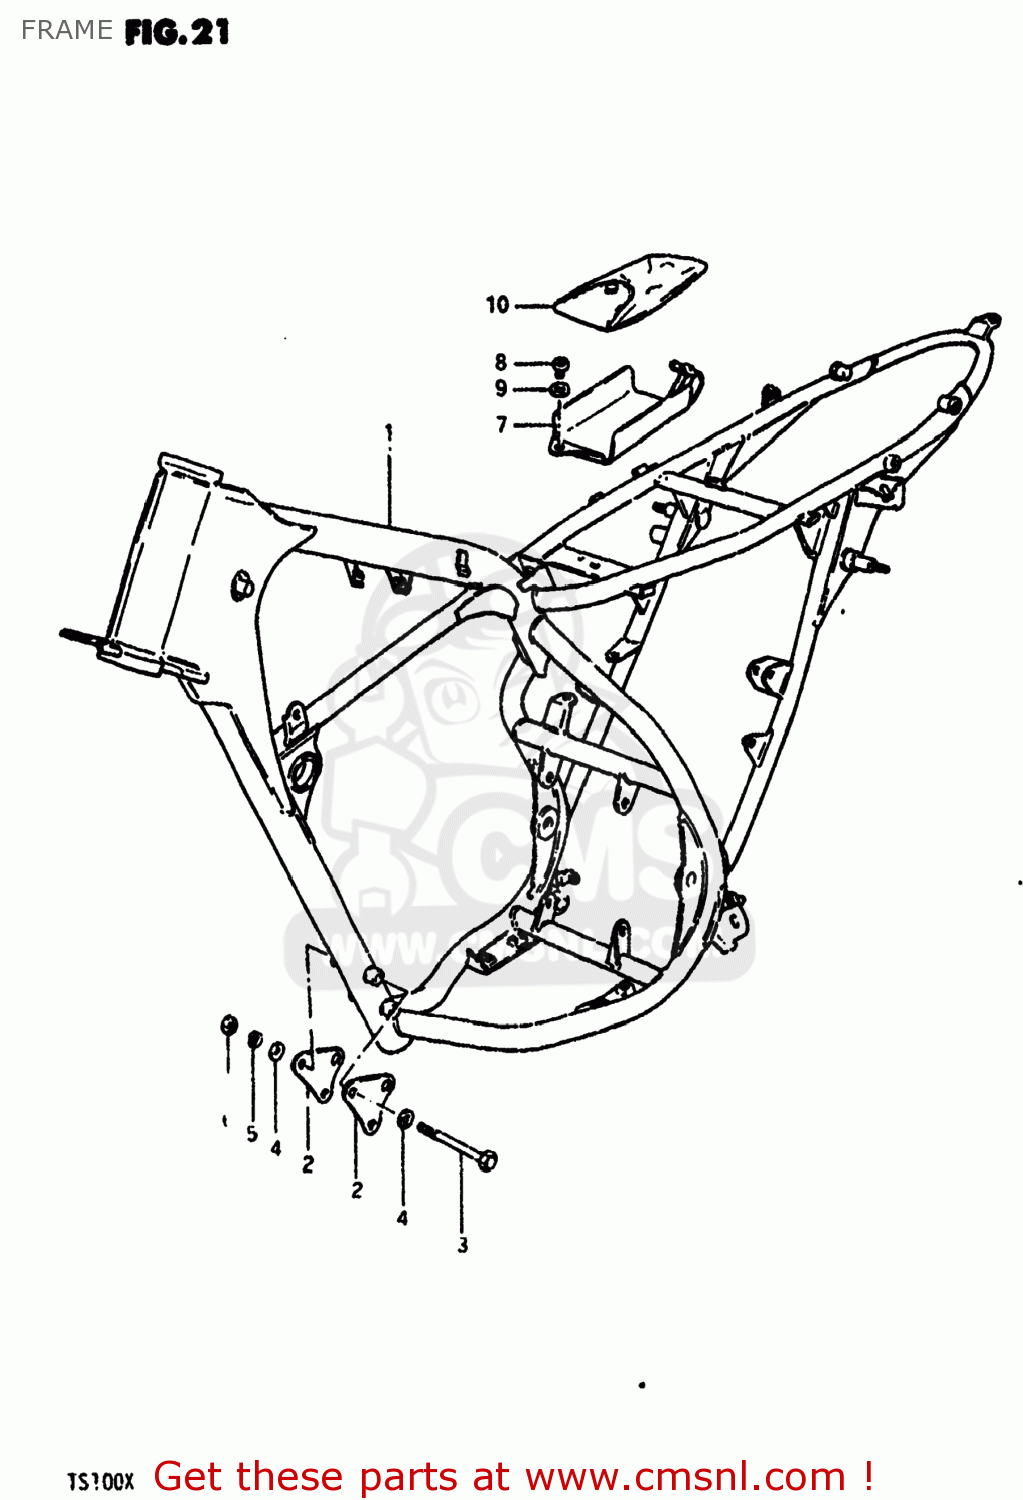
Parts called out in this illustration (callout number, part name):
1	FRAME
2	PLATE,ENG MTG
3	BOLT,8X75
4	WASHER
5	LOCK WASHER
6	NUT
7	HOLDER,TOOL
8	SCREW
9	WASHER
10	TOOL SET
